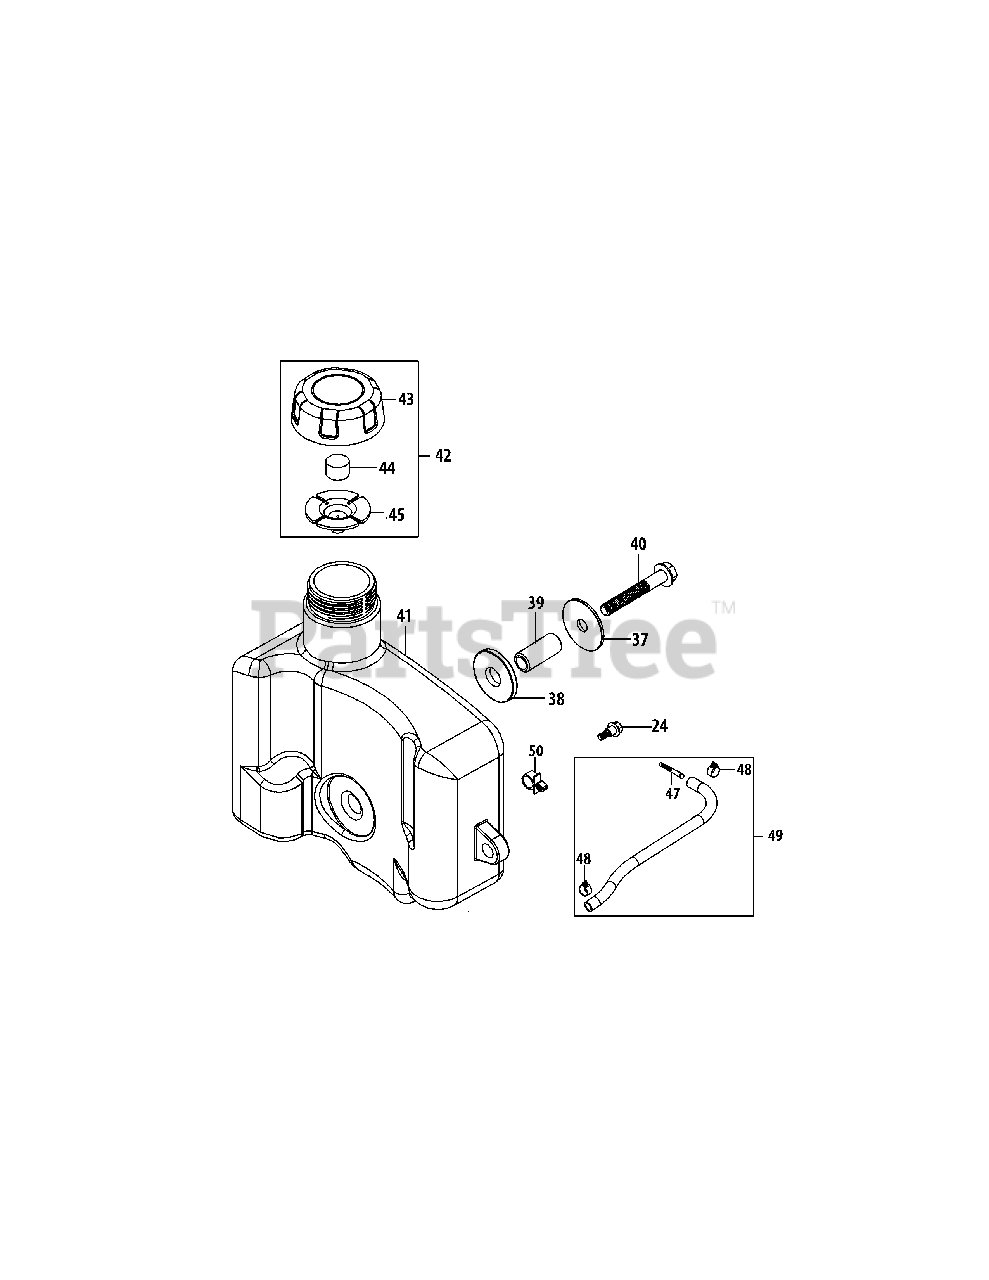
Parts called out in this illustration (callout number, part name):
24	Bolt M6×14
37	Fuel Tank Washer
38	Rubber Bushing
39	Fuel Tank Bushing
40	Bolt M8×50
41	Fuel Tank Assembly
42	Fuel Cap Assembly
43	Fuel Cap
44	Sponge Insert
45	Vent Gasket
46	Fuel Tank
47	Fuel Filter
48	Fuel Hose Clamp
49	Fuel Hose
50	Plastic Support Clamp
